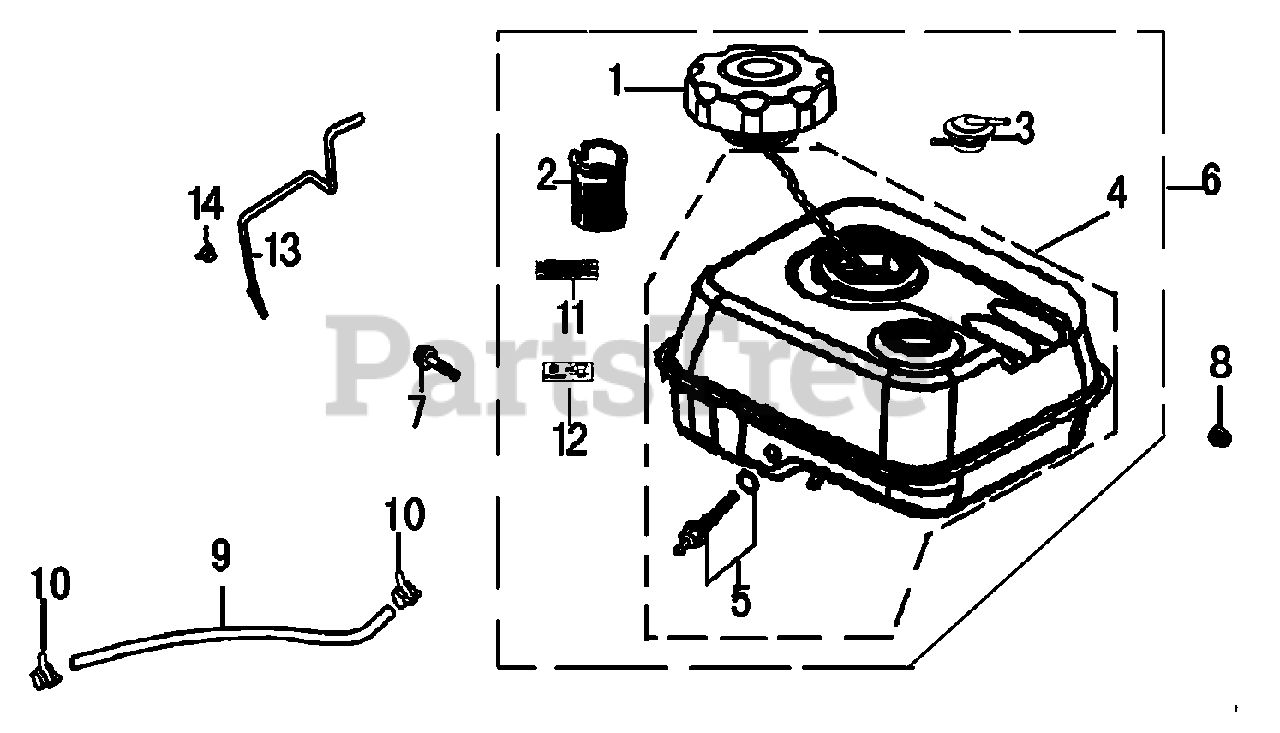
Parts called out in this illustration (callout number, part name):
1	CAP COMP., FUEL FILLER
2	FILTER, FUEL
3	GAS VALVE, FUEL TANK
4	TANK COMP., FUEL
5	JOINT ASSY., FUEL TANK
6	TANK, FUEL ASSY.
7	BOLT, FLANGE, 8x25
8	NUT, FLANGE
9	HOSE, FUEL
10	CLAMP, FUEL HOSE
11	WARNING MARK
12	REMINDER MARK
13	HOSE, PREFORMED
14	CLAMP, FUEL HOSE
